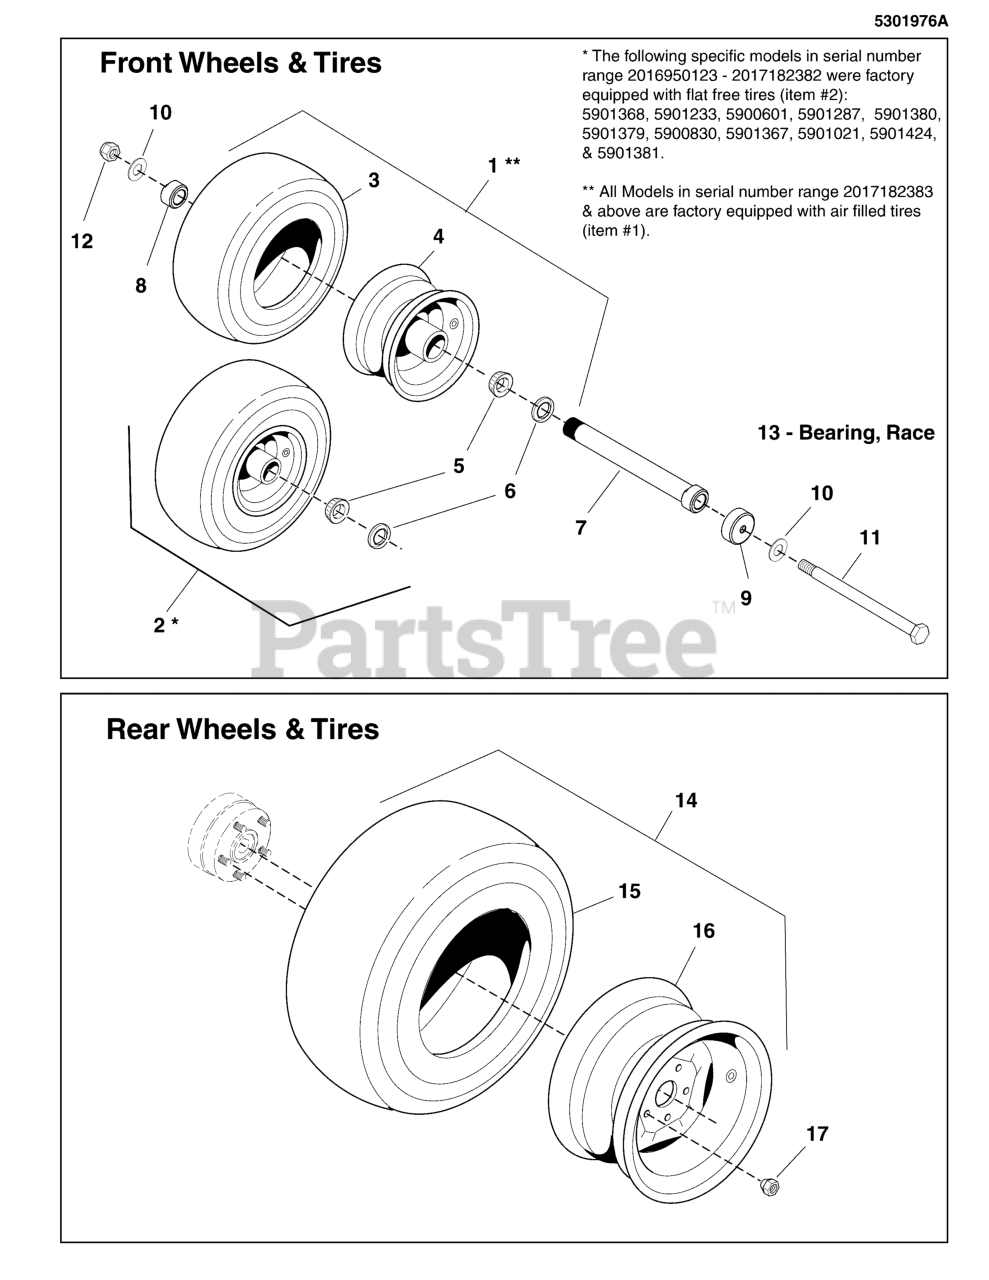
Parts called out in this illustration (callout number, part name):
1	TIRE ASSM, 13 X 6.5 - 6, PNE / TB
2	TIRE ASSM, 13 X 6.5 - 6, FF / TB
3	TIRE, RUBBER ONLY
4	WHEEL ASSEMBLY
5	BEARING, Tapered Roller
6	SEAL, GREASE
7	BEARING ADJUSTER, SPACER, 7.062 LG
8	NUT, BEARING ADJUSTER, AXLE
9	DEBRIS COVER, CASTER WHEELS
10	WASHER, 1/2 SAE
11	BOLT, 1/2-13 X 9 GD5 YZ
12	NUT, Hex Flange, Nylock, 1/2-13
13	BEARING, RACE
14	TIRE/WHEEL ASM, 24X12.00-12, TURF SMART
15	TIRE, 24X12.00-12, TURF SMART
16	WHEEL, 12 X 8.5
17	NUT, 1/2-20, FOR WHEEL BOLT SILVER
